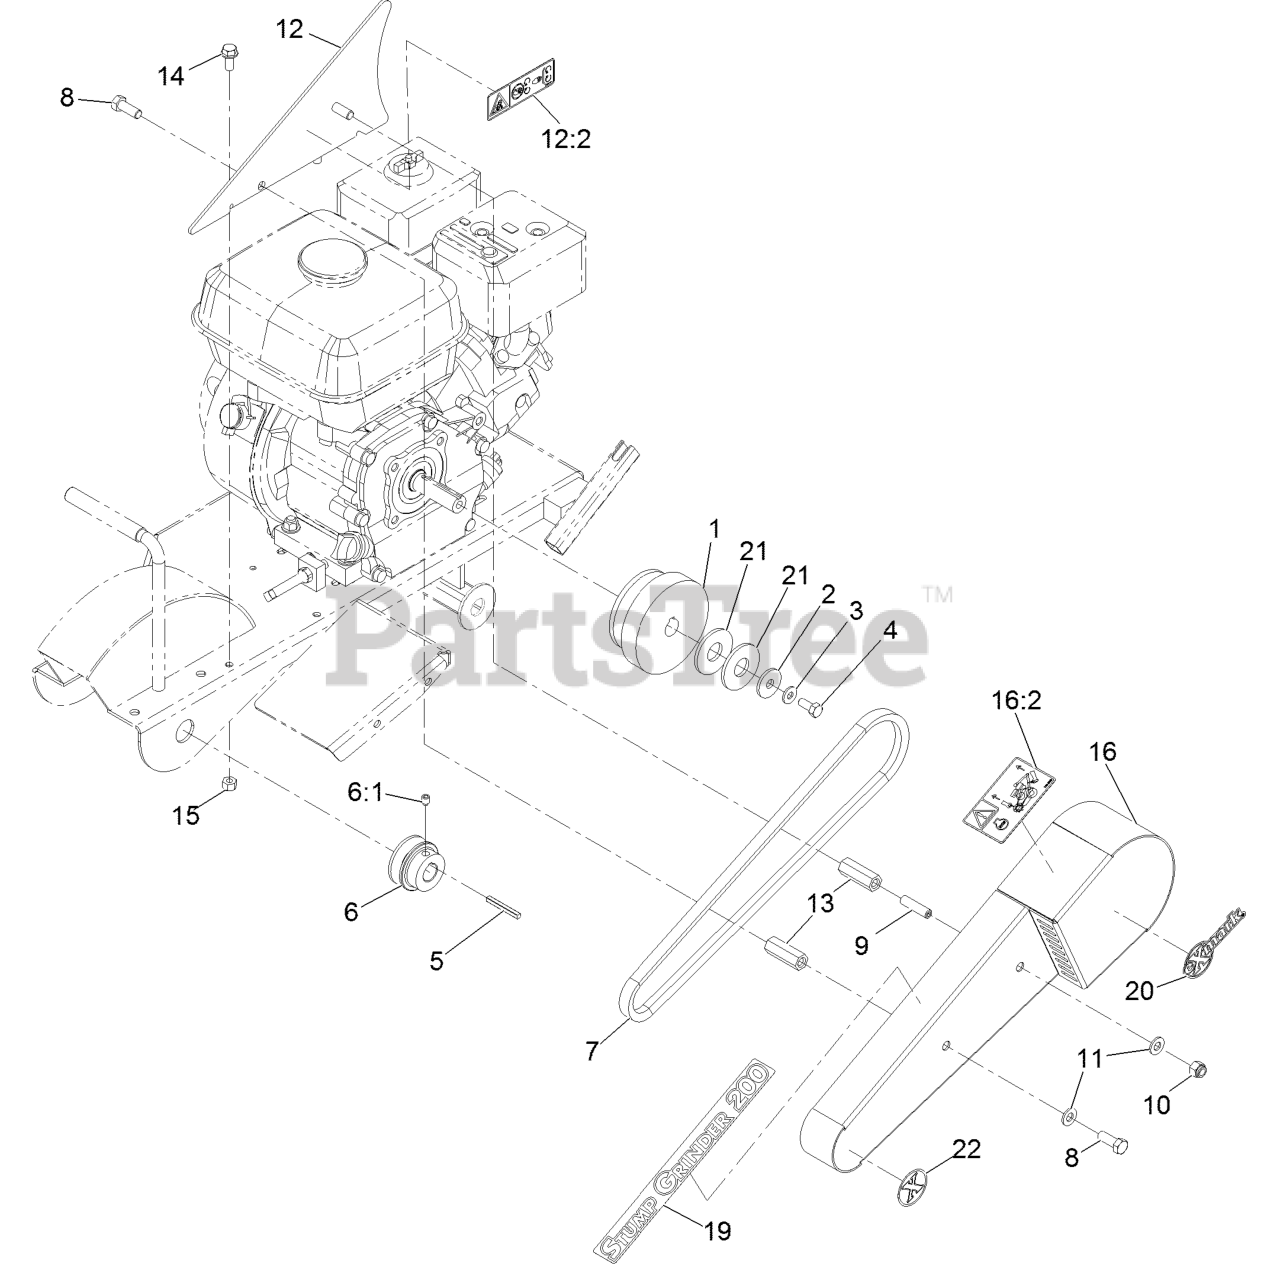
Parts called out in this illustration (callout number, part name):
1	CLUTCH-CENTRIFUGAL
3	WASHER-FLAT
4	SCREW-HH
5	KEY-SQUARE
6	PULLEY-FRONT
6:1	SCREW-HSH
8	SCREW-HH
9	SCREW-SET, HSH
10	NUT-LOCK, NI
11	WASHER-FLAT
12	PLATE-GUARD, INNER
12:2	DECAL-WARNING
13	SPACER-GUARD, BELT
14	SCREW-HHF
15	NUT-LOCK, NI
16	BELT GUARD ASM
16:2	DECAL-CAUTION
19	DECAL-STUMP GRINDER 200
20	DECAL,EXMARK
21	WASHER-FLAT
22	DECAL-EXMARK X-LOGO-1.63
